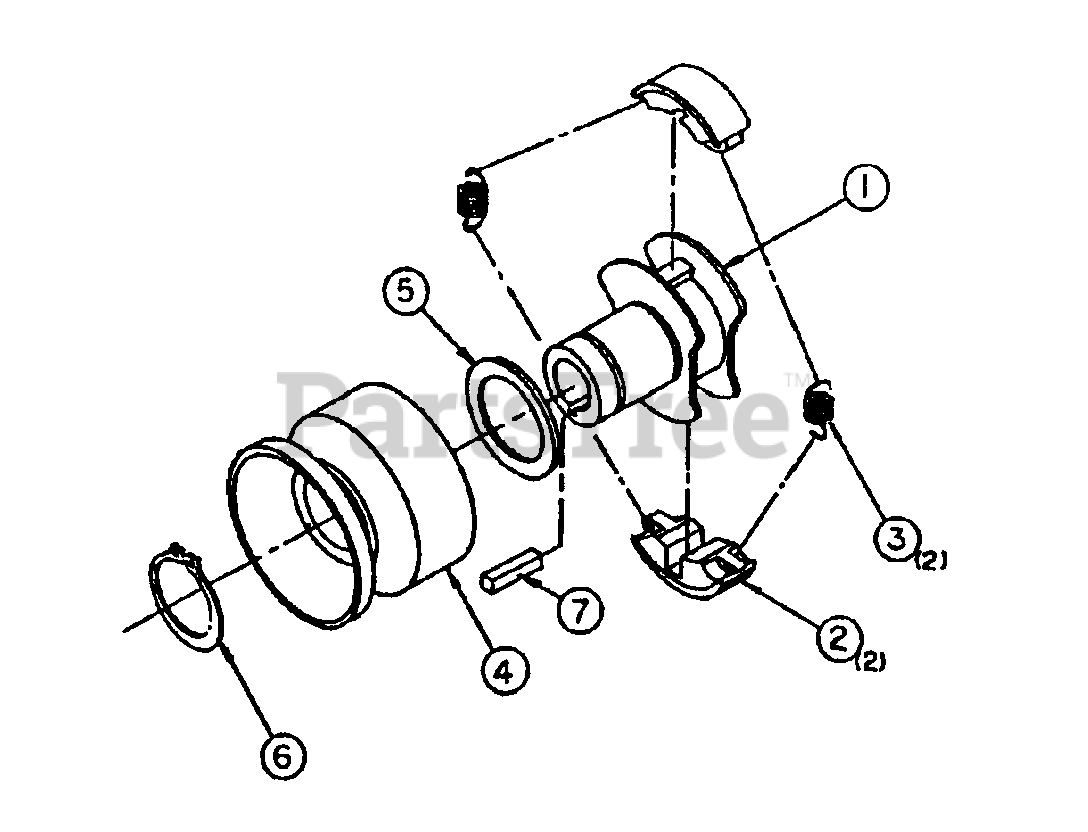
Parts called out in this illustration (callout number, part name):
1	Hub Assembly
3	Spring
4	Drum Assembly
5	Washer
6	Retaining Ring
7	KEY, 3/16x3/16x1"
